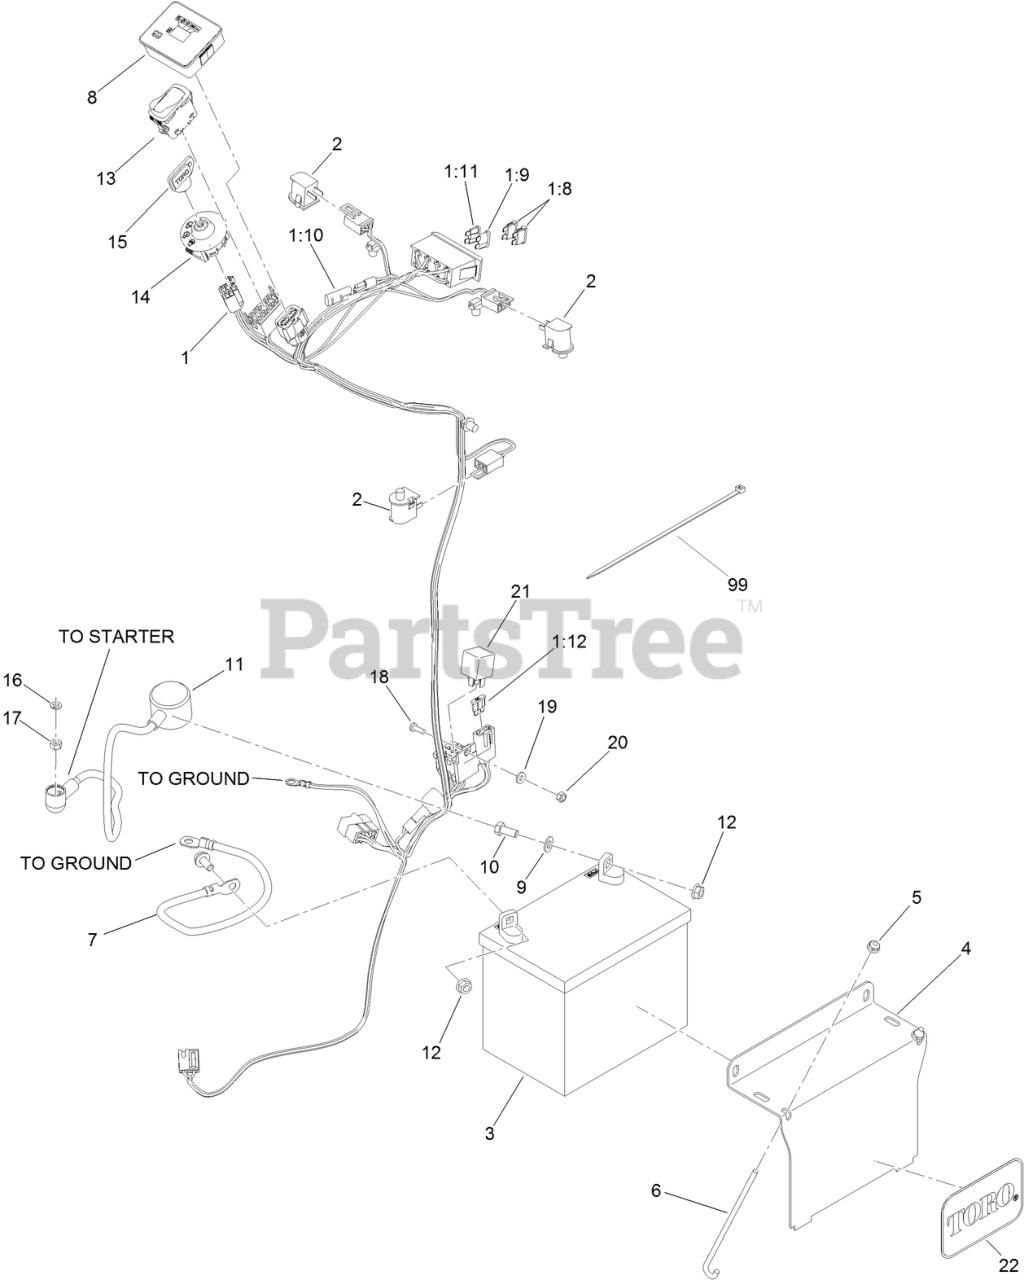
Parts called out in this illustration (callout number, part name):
1	HARNESS-WIRE
1:8	FUSE-BLADE, 15 AMP
1:9	FUSE-BLADE, 10 AMP
1:10	CAP-PLUG
1:11	FUSE-BLADE, 7.5 AMP
1:12	FUSE-BLADE, 30 AMP
2	SWITCH-BAIL
3	BATTERY-DRY
4	BRACKET-HOLD DOWN, BATTERY
5	NUT-HF
6	BOLT-HOLDDOWN
7	CABLE-BATTERY, BLACK
8	MODULE-METER, HOUR
9	WASHER-PLAIN
10	SCREW-HH
11	CABLE-BATTERY, POSITIVE
12	NUT-HHF, SMOOTH
13	SWITCH-ROCKER, (ON)-ON-OFF
14	SWITCH-IGNITION
15	KEY-IGNITION
16	WASHER-LOCK
17	NUT-HEX
18	SCREW-PPH
19	WASHER-FLAT
20	NUT-LOCK, NI
22	DECAL
99	TIE-CABLE
